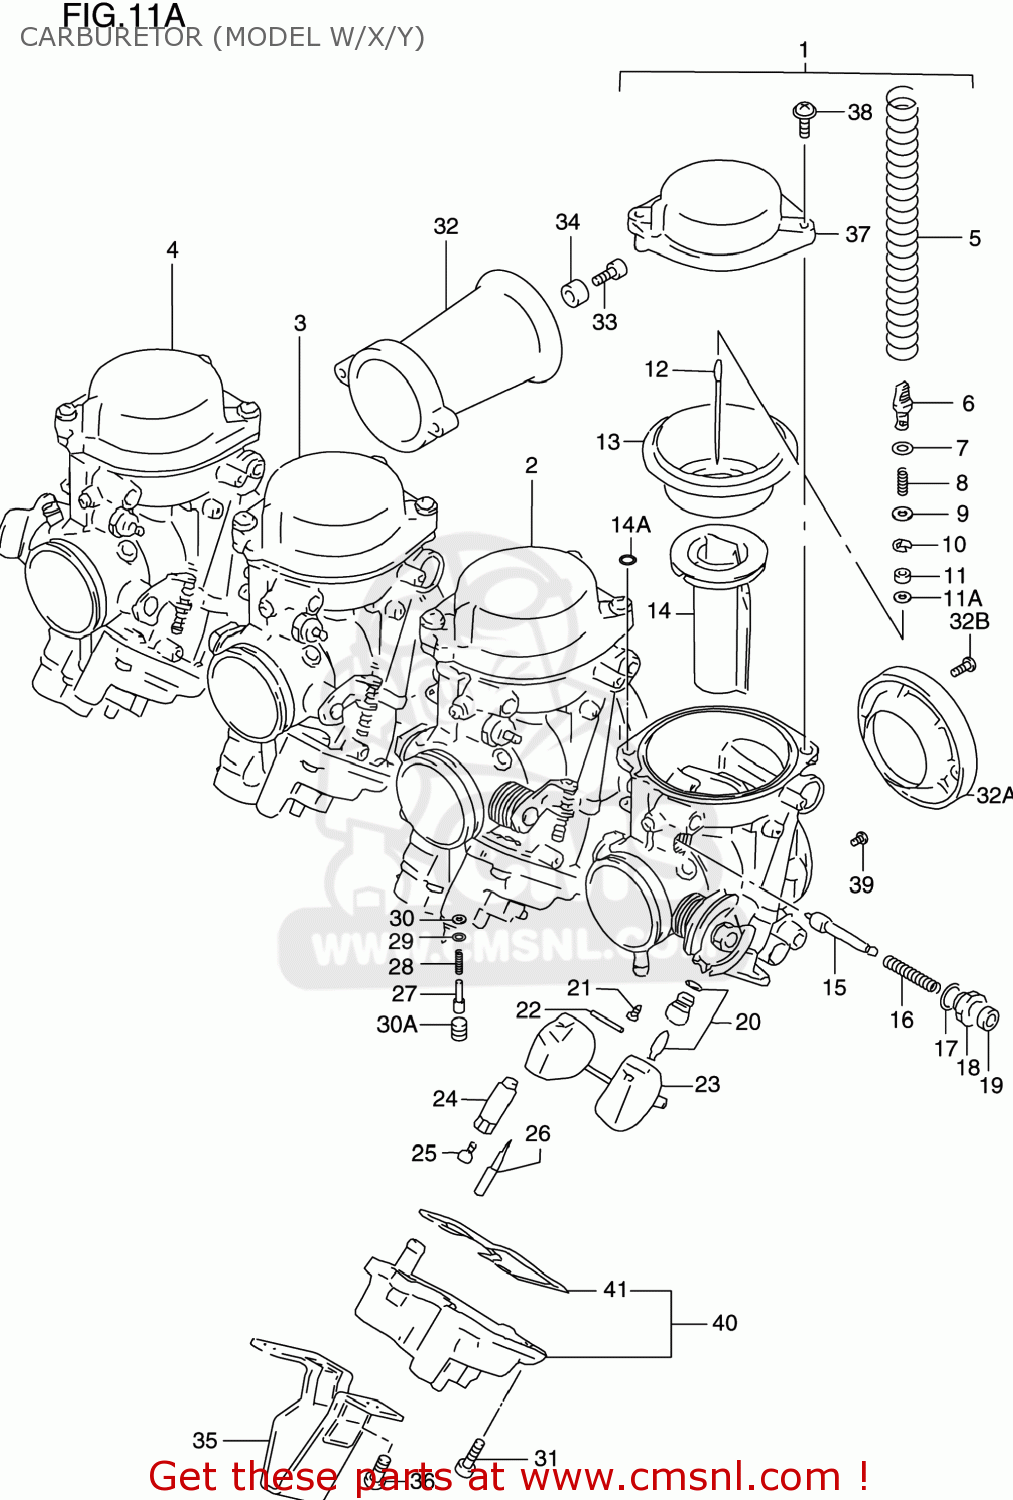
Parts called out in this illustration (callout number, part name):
1	CARBURETOR ASSEMBLY,LEFT
2	CARBURETOR ASSEMBLY,MIDDLE,LEFT
3	CARBURETOR ASSEMBLY,MIDDLE,RIGHT
4	CARBURETOR ASSEMBLY,RIGHT
5	SPRING
6	HOLDER
7	O RING(D:1.9,ID:4.8)
8	SPRING
9	WASHER
10	E RING,MULTIPLE JET NOZZLE
11	RING
11A	WASHER
12	NEEDLE,JET
13	DIAPHRAGM
14	VALVE,PISTON
14A	O RING
15	PLUNGER
16	SPRING
17	O RING
18	GUIDE SCREW,PLUNGER
19	CAP,STARTER VALVE
20	VALVE ASSY,NEEDLE(NI)
21	SCREW
22	PIN,FLOAT
23	FLOAT ASSY
24	HOLDER,JET
25	JET,MAIN (132.5)
26	JET,PILOT(12.5)
27	ADJUSTER
28	SPRING,THROTTLE SCREW
29	WASHER
30	O RING,PILOT AIR SCREW
30A	PLUG
31	SCREW
32	FUNNEL
32A	FUNNEL
32B	SCREW
33	SCREW
34	RING
35	BRACKET
36	SCREW
37	COVER ASSY,DIAPHRAGM
38	SCREW
39	JET,MAIN(140)
40	BODY ASSY,FLOAT,L
41	O RING
